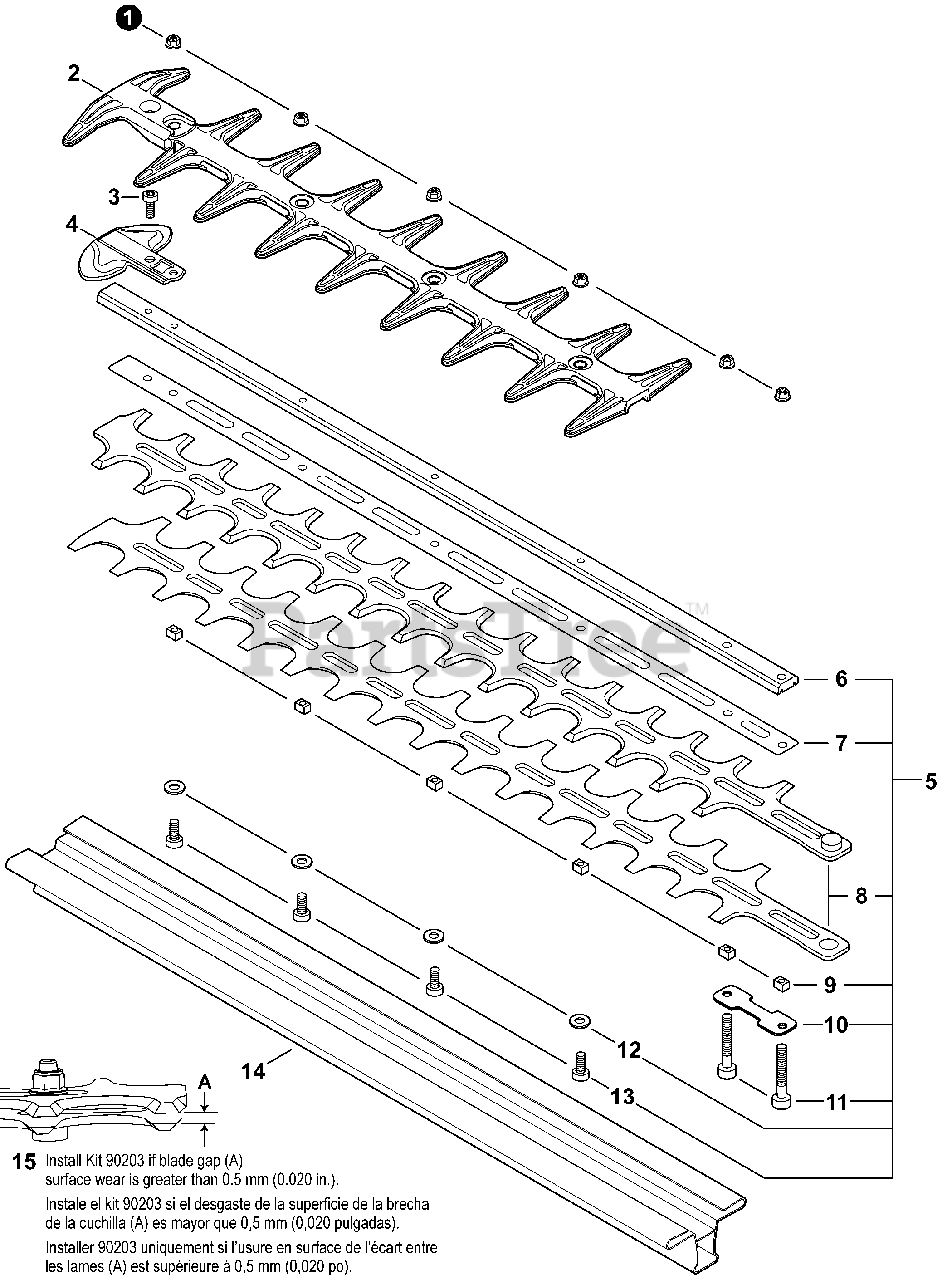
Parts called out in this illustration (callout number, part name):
1	NUT, FLANGE M5
2	GUARD, CUTTER BLADE
3	BOLT, TORX 5×8
4	GUARD, TIP
5	CUTTER ASSY, 20"
6	SUPPORT, CUTTER 20"
7	PLATE, CUTTER 20"
8	CUTTER, 20"
9	GUIDE, BLADE 5
10	PLATE, EYE
11	BOLT, TORX 5×30
13	BOLT, TORX 5×25
14	SCABBARD
15	BLADE KIT, ADJUSTABLE
